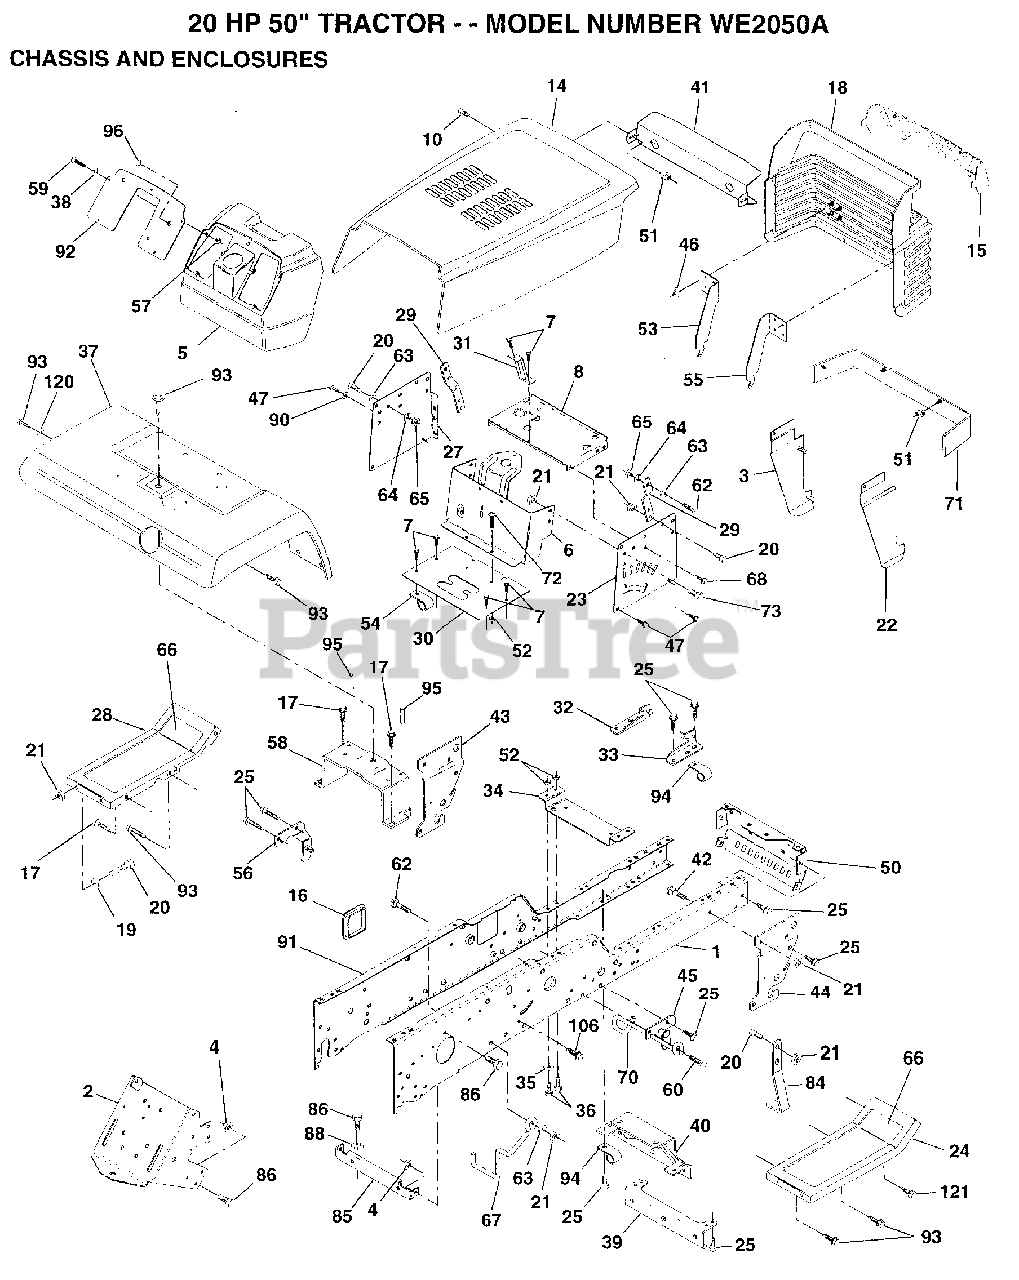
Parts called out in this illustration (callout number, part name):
2	DRAWBAR, GT
4	NUT.7/16
6	DASH ASM LOWER
7	SCREW
8	SUPPORT BATRY VGT
10	SCREW SPECIAL
16	COVER ACCESS
17	SCREW
18	GRILLE ASM WELD
19	WASHER
20	BOLT
21	NUT
25	SCREW
26	SCREW
29	BRKT.SUPT.DASH
30	SADDLE SILKSCRN
31	BRACE.SUPT.STRG
32	BRACKET ASM FRAME
33	BRACKET ASM FRAME
34	BRACKET.ENG.SUPT.
35	WASHER
36	BOLT
38	WASHER PM
39	BRACKET.AXLE.FRT.
43	BRACKET.SUS.FT.LH
44	BRACKET, SPNSN FR. RH
47	SCREW LT
50	BRACKET.CHASSIS.
51	PAL NUT LT
52	NUT
53	BRACKET.RH
54	"CLIP,INSULATOR"
55	BRACKET.LH
57	NUT
58	BRKT.ASM.FENDER
59	SCREW
60	SCREW
62	BOLT D
63	WASHER
64	LOCKWASHER
65	NUT.HEX.3/8-16UNC
66	FOOTREST PAD
67	GUIDE BELT TRANS
68	SCREW LT
70	GUIDE.BELT.MID.SP
72	SCREW
73	BOLT
84	STOP.OVER.CENTER
86	BOLT
88	LOCKWASHER
90	LOCKWASHER
92	PLATE, SILKSCREEN DASH
93	SCREW LT
94	CLIP GTV
95	NUT-PUSH YT
96	PLUG-DASH T
106	BOLT.5/16-18X1.25
120	WASHER HYT
121	PAL NUT
